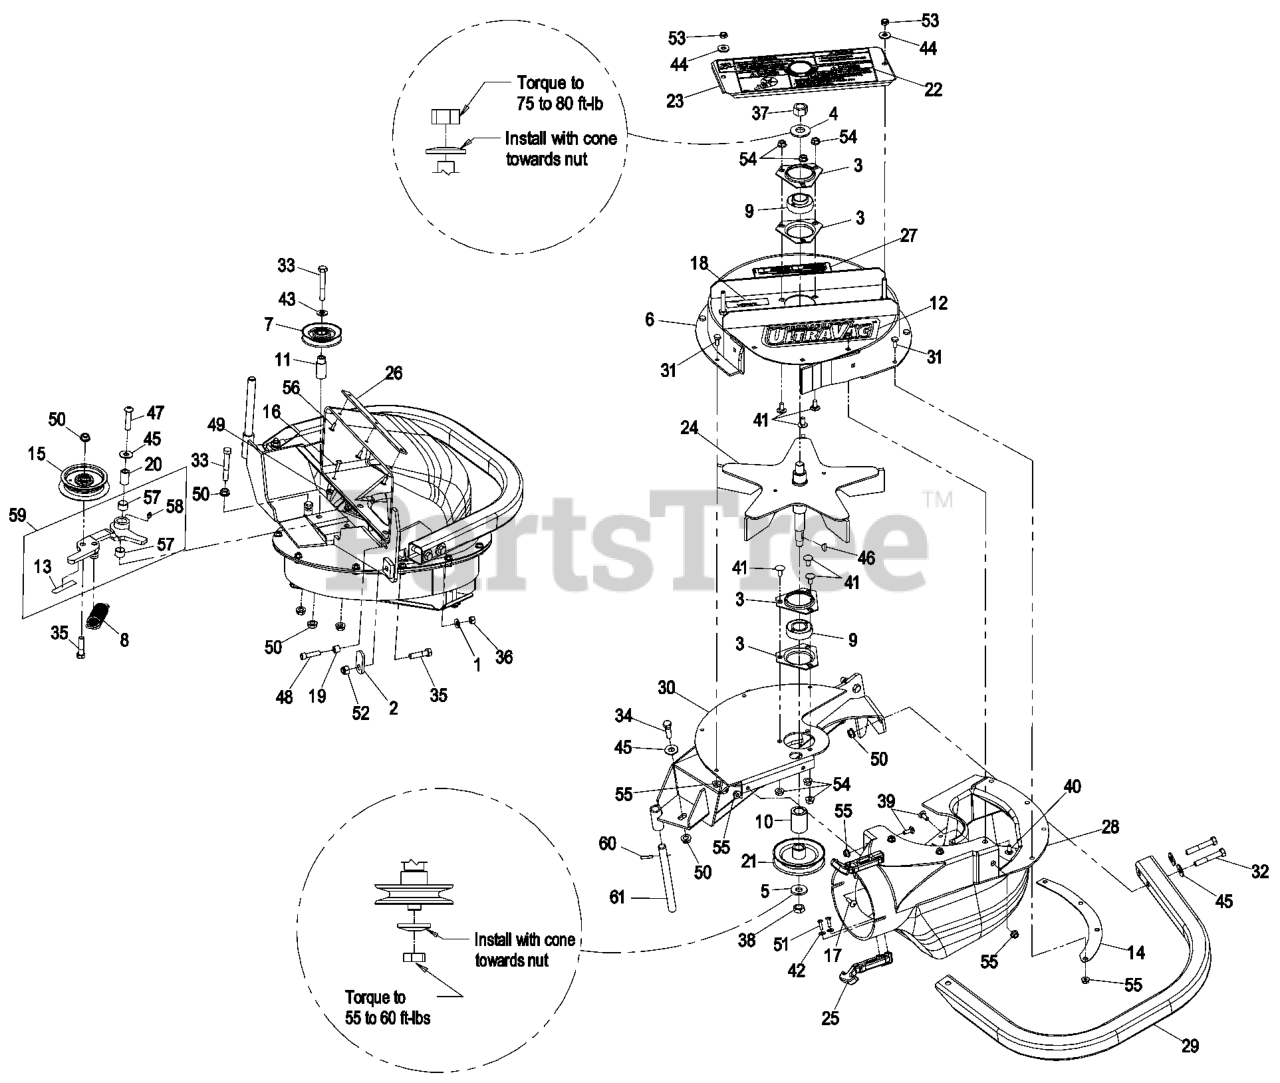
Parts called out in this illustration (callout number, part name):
1	WASHER-SPRING
2	LATCH-CATCHER, GRASS
3	HOUSING-FLANGE
4	WASHER-SPRING
5	WASHER-SPRING
6	ASM,UPPER HOUSING
7	IDLER-INSIDE
8	SPRING-IDLER
9	BEARING
12	DECAL, ULTRA VAC
13	DECAL-WARNING
14	PLATE-BACKING, BLOWER
15	IDLER-FLAT
16	SCREW-HEAD, TRUSS
18	DECAL-COVER, MISSING
19	BUSHING, LOCATOR
20	BUSHING-PIVOT, IDLER
21	SHEAVE-BLOWER
22	DECAL-WARNING
23	ASM, BEARING COVER
24	IMPELLER
25	LATCH-RUBBER
26	PLATE-REINFORCEMENT
27	DECAL,WEIGHT
28	ASM,BLOWER CHUTE LHP
30	WELD, FRAME SM BLOWER
31	SCREW-HH
32	SCREW-HH
33	BOLT-CARR
34	SCREW-HH
35	SCREW-HH
36	NUT-HEX
37	NUT-HEX
38	NUT-JAM
39	BOLT-CARR
40	SCREW-CARR
41	SCREW-CARR
42	WASHER-FLAT
43	WASHER-FLAT
44	WASHER-FLAT
45	WASHER-FLAT
46	KEY-WOODRUFF
47	SCREW-HSBH
48	SCREW-HSH
50	NUT-HHF, WHIZ
51	SCREW-PPH
52	NUT-LOCK, NI
53	NUT-LOCK, NI
56	RIVET-BLIND
57	BUSHING
58	FITTING-GREASE
59	ASM, IDLER ARM - SERVICE
60	PIN-ROLL
61	SHAFT-CATCHER, GRASS
